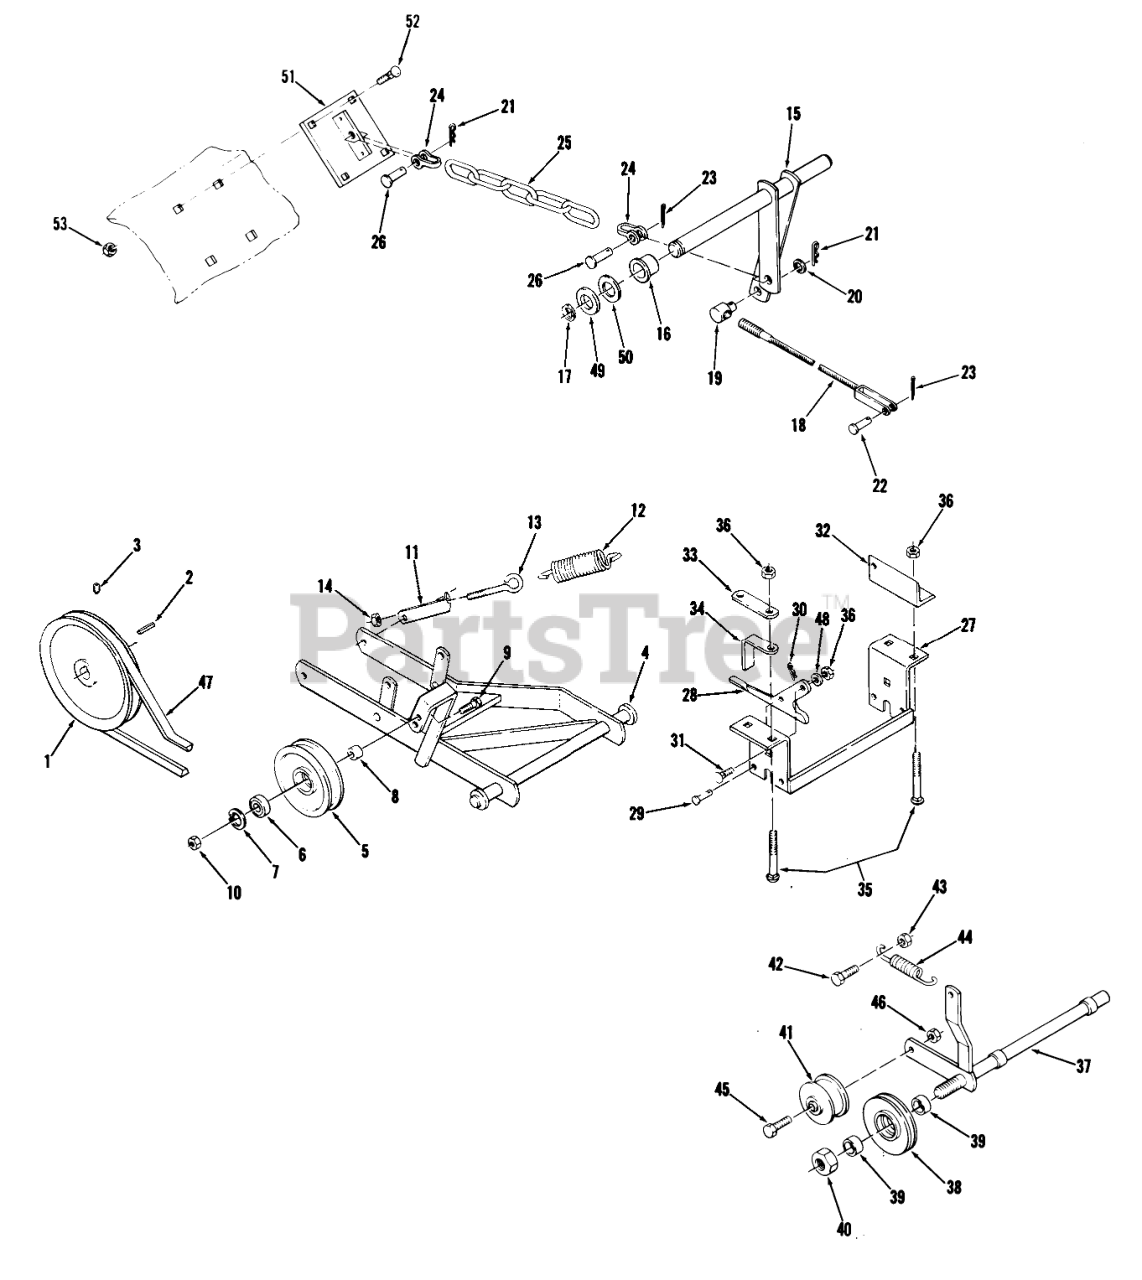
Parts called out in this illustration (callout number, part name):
1	Pulley
2	KEY-STRAIGHT
3	Setscrew-Square Head
4	Hitch
5	PULLEY IDLER
6	BEARING
7	INTERNAL SNAPRING
8	SPACER
9	HEX HD CAP SCREW
10	Nut
11	Bracket-Spring
12	SPRING
13	EYEBOLT
14	NUT
15	Lever Assy.
16	BUSHING
17	E-RING
18	ASSY-LIFT CABLE
19	TRUNNION-CLUTCH ROD
20	Washer
21	Hairpin
22	Pin
23	Cotter Pin
24	Clevis
25	CHAIN-LIFT
26	Clevis Pin
27	Bracket
28	PLATE-LATCHING
29	Pin
30	Hairpin
31	Bolt
32	Link
33	BRACKET-REAR LINK MOUNTING
34	SPACER-BRACKET
35	Bolt-Carriage
36	Nut
37	Front Idler
38	Pulley-V
39	Spacer
40	Nut
41	IDLER PULLEY
42	BOLT
43	Nut
44	SPRING-BRAKE
46	Nut
47	V BELT
48	Washer
49	WASHER
50	WASHER-SHIM
51	Lift Plate
52	Bolt
